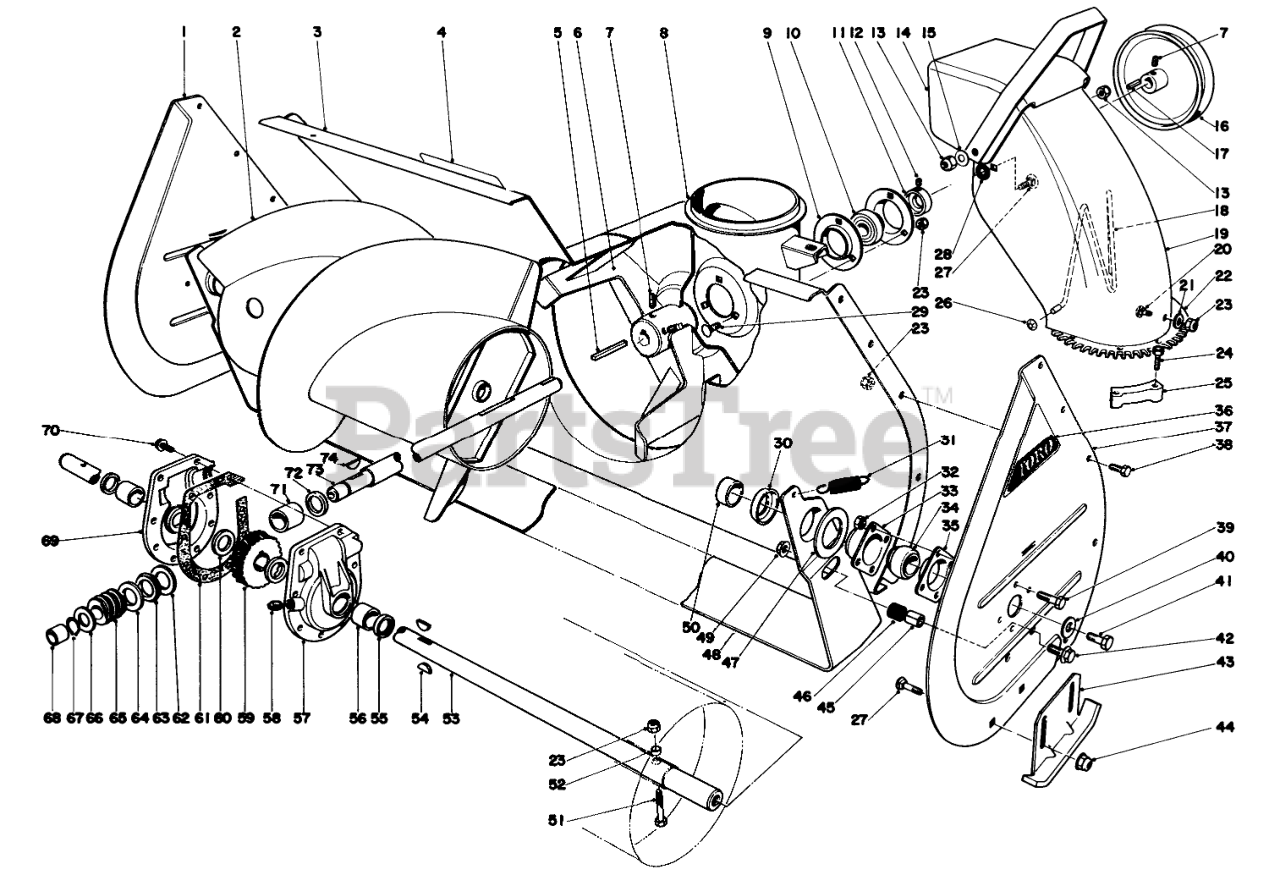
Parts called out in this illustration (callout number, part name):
1	Side Plate
2	RH AUGER ASM - 32"
3	AUGER HSG WA 26" R
4	Decal-Warning
6	IMPELLER ASM
7	SCREW-SET, SQH
8	CHUTE RING
9	BRG FLANGE
10	BALL BRG W/COLLAR
11	EXT LOCKING COLLAR
12	SCREW-HSH
13	NUT-LOCK, CONE
14	Deflector
15	WASHER-BELLEVILLE
16	1/2 X 9.5 DIA PULLEY
17	SQUARE KEY
18	WIRE-CHUTE
19	Upper Chute
20	SCREW-CARR
21	WASHER-PLAIN
22	Screw
23	NUT-LOCK, NI
24	SCREW-SPECIAL
25	RETAINER-CHUTE
26	NUT-PUSH
27	SCREW-CARR
28	WASHER-RUBBER
29	BOLT-CARR
30	Positioner-Scraper
31	SPRING-TENSION
32	NUT-LOCK, CONE
33	BEARING-FLANGE, FRONT
34	BEARING
35	BEARING-FLANGE, REAR
36	AUGER SIDE PLT DECAL
37	Side Plate L. H.
38	SCREW-HH
39	SCREW-HH
40	WASHER
41	SCREW-HH
42	SCREW-HHF
43	AUGER SKID WA R
44	NUT-HHF, WHIZ
45	SCRAPER STOP SPACER
46	SCRAPER STOP CUSHION
47	SCRAPER BLADE SPACER
48	SCRAPER BLADE 32" R
49	NUT-HF
50	AUGER SPACER
51	Auger Bolt
52	SPACER-HUB, AUGER
53	32 AUGER SHAFT
54	KEY-WOODRUFF
55	SEAL-OIL
56	BUSHING
57	Gear Case L.H. (Incl. Ref. #55-56)
58	PLUG-PIPE, SQH
59	GEAR-WORM, 27T
60	WASHER-THRUST
61	Gasket
62	WASHER-THRUST
63	BEARING-THRUST
64	THRUST-WASHER
66	WASHER-THRUST
67	Ring-Snap
68	BUSHING
69	Gear Case R.H. (Incl. Ref. #55-56)
70	SCREW-HWHTF
71	BUSHING-SPECIAL
72	RING-QUAD
73	SHAFT-IMPELLER
74	KEY-WOODRUFF
